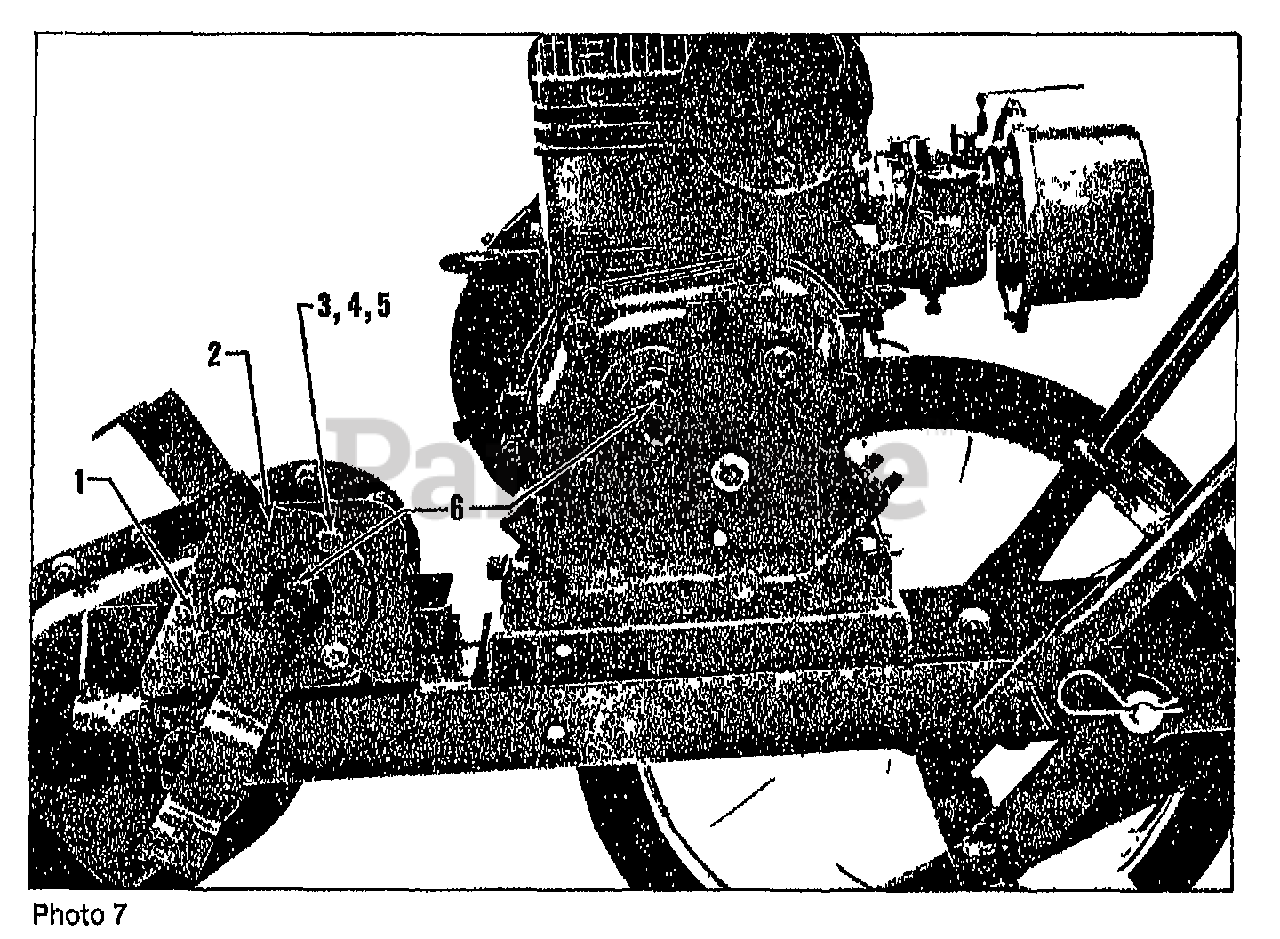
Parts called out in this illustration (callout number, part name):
1	DRIVE GUARD MOUNTING BRACKET
2	DRIVE GUARD PIVOT BRACKET
3	SCR-HH 1/4-20X.625 (ATTACHES PIVOT BRACKET TO MOUNTING BRACKET)
4	WASHER-FLAT 1/4 SAE
5	NUT-LK 1/4-20
6	KEY-.188 SQ X 1.25 (1 USED IN TRANS- MISSION SHAFT & 1 USED IN ENGINE SHAFT)
